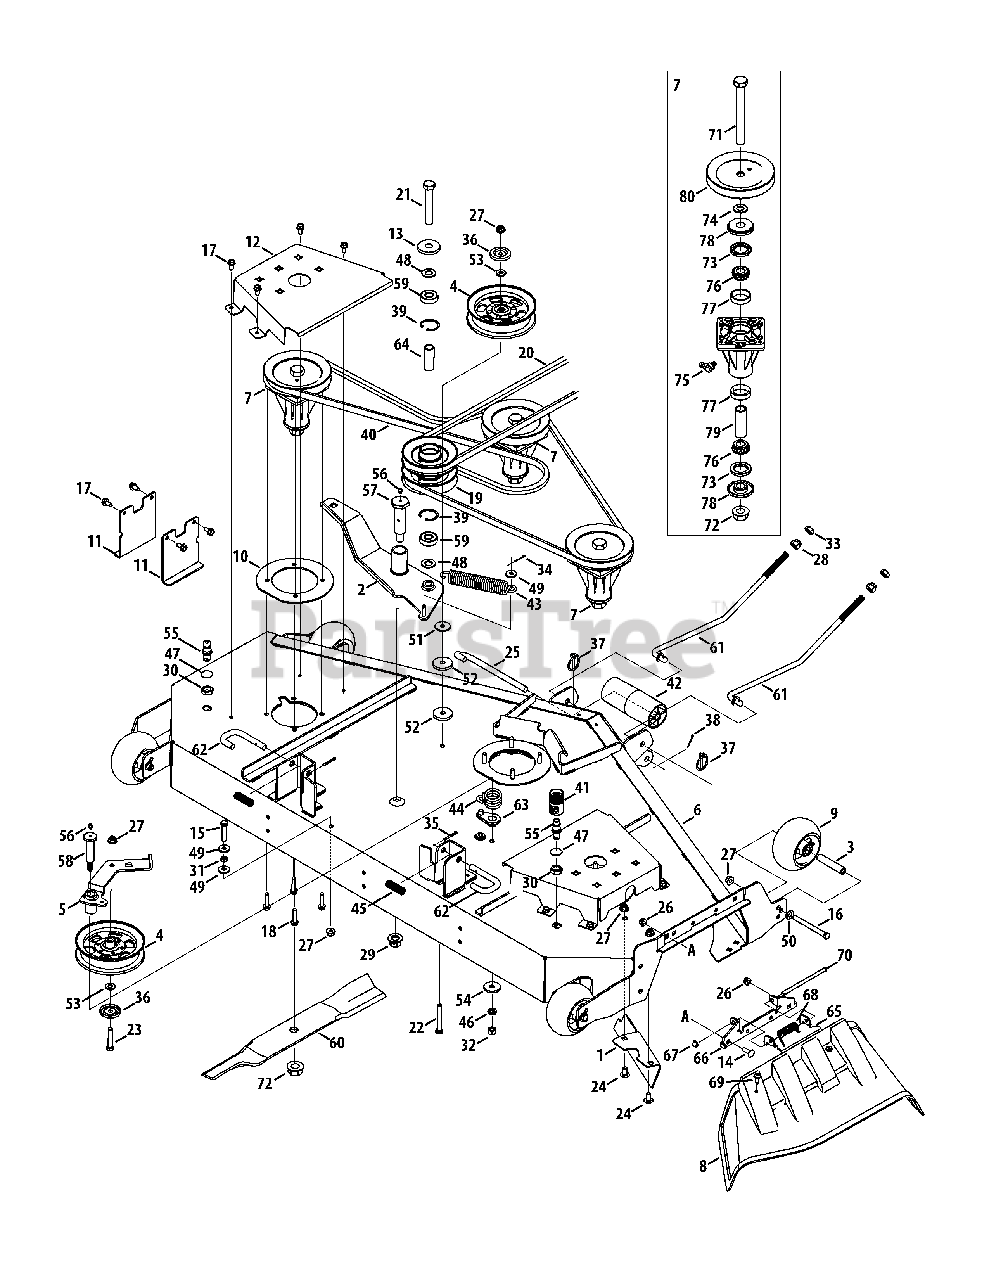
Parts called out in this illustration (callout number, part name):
2	PTO Idler Assembly
3	Spacer, .390 x .620 x 3.04
4	Idler Pulley, 5.00 Dia.
6	Deck Assembly
7	Spindle Assembly
8	Discharge Chute Assembly
9	Wheel, 5.0
10	SPINDLE REINFORCEMENT PLATE (POWDER BLACK)
11	Up-Stop Bracket
13	Pulley Cap
14	Carriage Screw, 5/16-18 x 1.00
15	Hex Screw, 3/8 x 16 x 1.75
16	Hex Screw, 3/8 x 16 x 4.00
17	SCREW 5/16-18 x .750
18	Hex Washer Screw, 5/16-18 x 1.50
19	Double Pulley
21	Hex Screw, 5/8 x 18 x 4.0
22	Hex Cap Screw, 3/8 x 16 x 2.75
23	Hex Cap Screw, 3/8 x 16 x 2.00
24	CARRIAGE BOLT 3/8-16 x .75
25	Roller Pin, 1/2 x 7.31
26	Flange Lock Nut, 5/16-18
27	Flange Lock Nut, 3/8-16
28	Flex Lock Nut, 1/2-13
29	Flange Lock Nut, 5/8-18
30	Hex Nut, M16-1.5
31	Jam Nut, 3/8-16
32	Hex Nut, 7/16-14
33	Nut, Jam, 1/2-13
34	Cotter Pin 3/32" Dia. x 1" Lg.
35	Cotter Pin, 5/32 x 1.25
36	Pulley Cap
37	Pin, Lynch x .1875
38	Cotter Pin, 3/32 x 1.25
39	Retainer Ring
41	Water Nozzle Adapter
42	Front Roller
43	Extension Spring, 1.25 x 6.9
44	Idler Torsion Spring, 1.10 x 1.3
45	Compression Spring, .66 x 1.8
46	Lock Washer, 7/16
47	Lock Washer, 5/8
48	Flat Washer, .650 x 1.250 x .075
49	Falt Washer, .385 x 1.00 x .135
50	Flat Washer, .406 x .875 x .059
51	Flat Washer .38 x 1.38 x .125
52	Flat Washer, .4375 x 1.75 x .25
53	Flat Washer, .406 x .875 x .105
54	Flat Washer, .45 x 1.5 x .172
55	Deck Water Nozzle
56	Drive Lube Fitting, 3/16
57	SHOULDER BOLT 1.0 x 3.0 5/8-18
58	SHOULDER BOLT .68 x 2.44 7/16-14
59	Ball Bearing, .625 x 40 x 12
60	Blade, 21.00
60	(Cub Cadet) 60" BLADE SET (942-04415)
61	Front Hanger Rod
62	Mower Support Pin
63	Retainer Spring
64	Spacer, .88 x .635 x 2.30
67	PUSH CAP
68	Torsion Spring
69	TORX SHOULDER SCREW 1/4-20
70	Chute Rod
71	Hex Cap Screw, 3/4-16 x 6.50
72	Nut, 3/4-16, Flangelock
74	Flat Washer, .76 x 1.49 x .06
75	Grease Fitting, 3/16
76	Cone Bearing, Tapered Roller, .750
77	Cup, Bearing
78	DECK SPINDLE SPACER
79	Spacer, .78 x 1.00 x 2.895
80	V-Type Pulley
